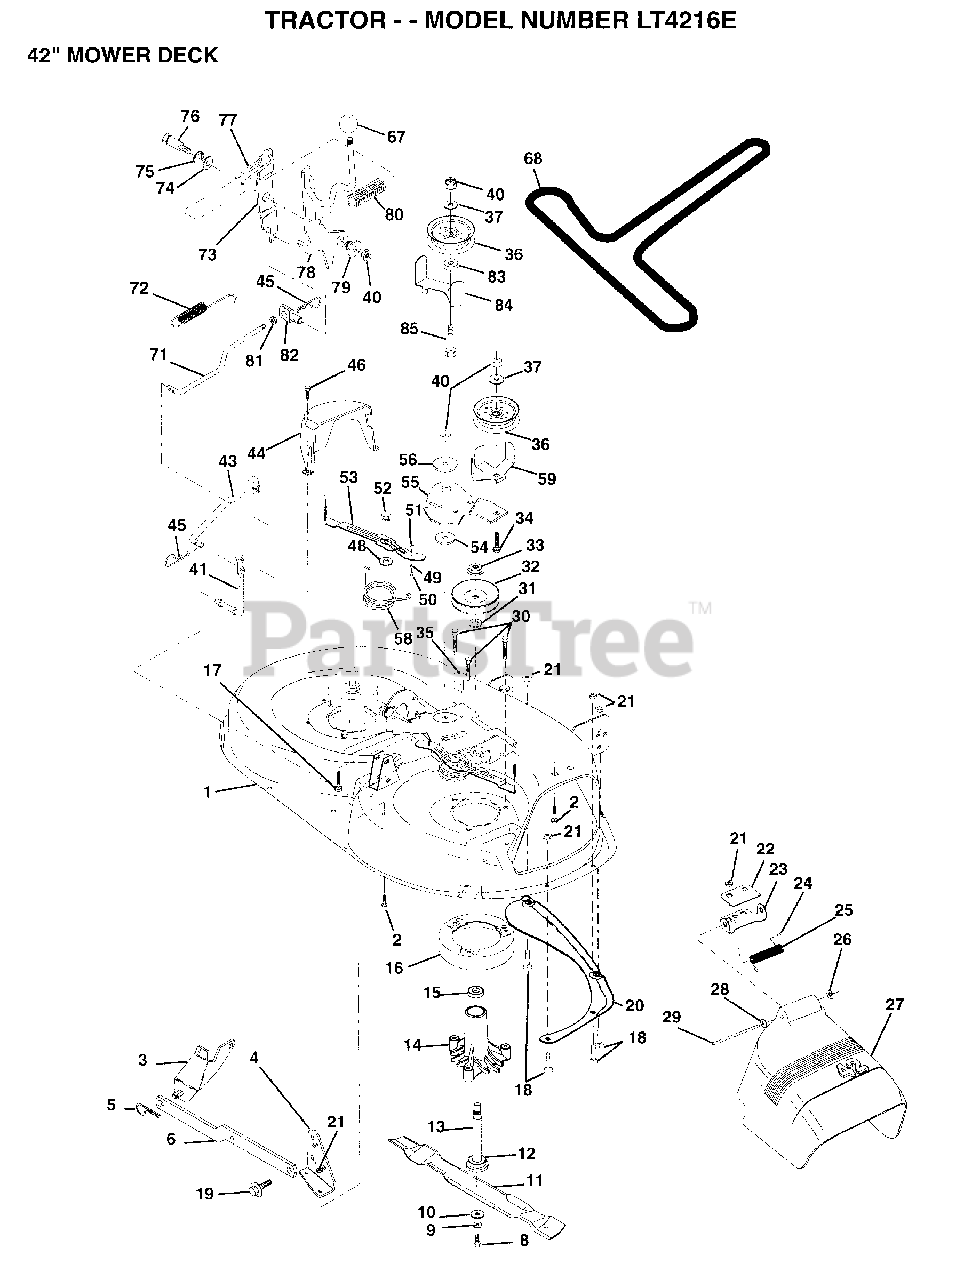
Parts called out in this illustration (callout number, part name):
1	DECK.WELD.42.
2	BOLT
3	BRKT ASM SWAY BAR
4	BRKT DECK SW BAR
8	BLADE BOLT
10	WASHER.HARD.BLADE
11	"BLADE.42"" HIPERF"
12	BEARING.BALL
14	HSG ASM MANDREL
15	BEARING
16	STRIPPER RND MWR
17	BOLT RDHD 3/8-16
18	BOLT
19	BOLT SHD 5/16-18
22	STIFFENER BRKT
23	DEFLECTOR BRKT
24	CAP-SLEEVE LT
25	SPRING TORSION
26	NUT PUSH M
27	DEFLECTOR.SHIELD
28	WASHER
29	HINGE ROD
31	WASHER
34	BOLT
35	XMAS TREE FASTNER
36	FLAT IDLER PULLEY
37	WASHER
41	PIVOT ROD
43	ROD CLUTCH W/NIBS
44	GUARD MAND LH BLK
45	RETAINER M
46	SCREW.1/4-20X5/8
48	HARD SMALL WASHER
50	SHOULDER BOLT
51	LOCKNUT
52	BOLT.SHLD.5/16-18
53	BRAKE PAD ARM ASM
54	HARDENED WASHER
56	SPACER RETAINER
58	SPRING TORSN BRAK
59	GUARD IDLER TUV
67	KNOB T (1/2-HOLE)
68	BELT.V.T-PATH
71	ROD CLUTCH 38/42
72	RETURN SPRING
73	CLUTCH ARM SECOND
74	WASHER
75	RING
76	SHOULDER BOLT
77	SPRING KEEPER
79	BUSHING
81	NUT
82	TRUNION ADJ
83	WASHER
85	BOLT RDHD 3/8-16
